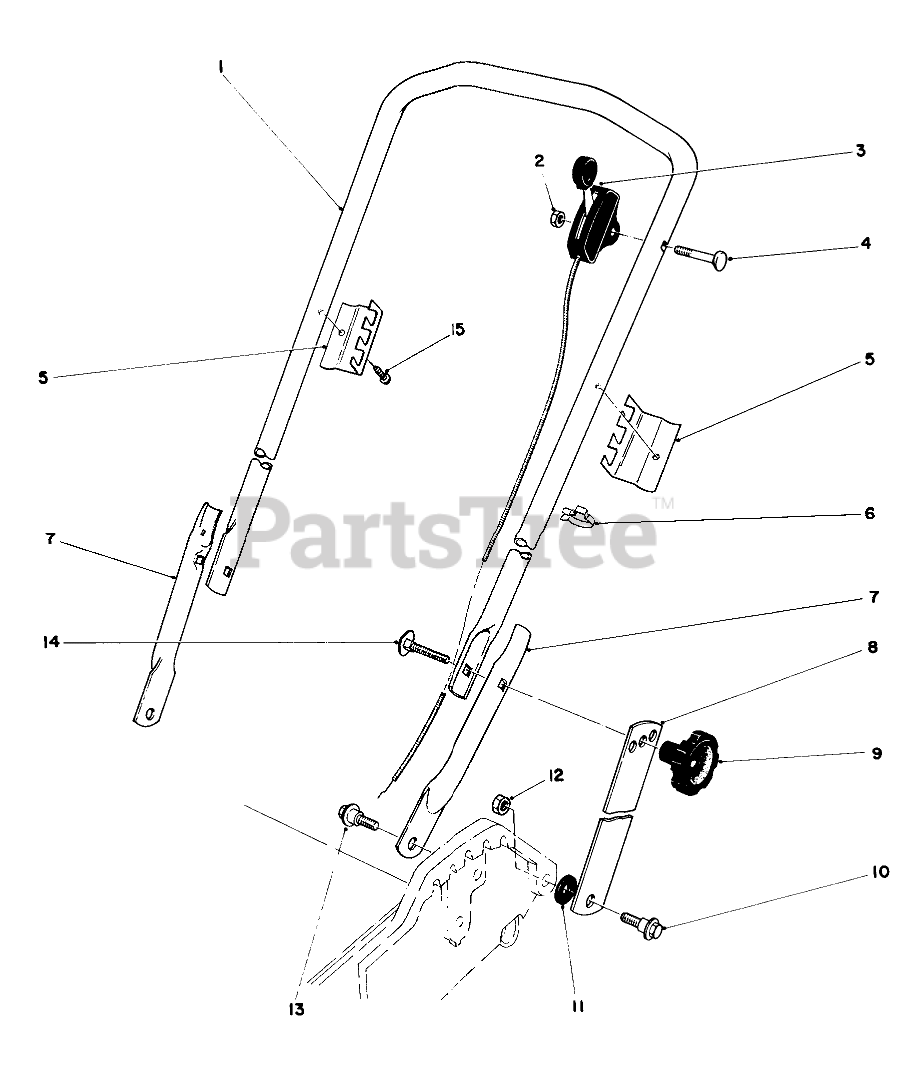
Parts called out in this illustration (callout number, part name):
1	Upper Handle (Incl. #3)
2	NUT-LOCK, NI
3	SERVICE THROTTLE CONTRO
4	SCREW-HANDLE
5	Bag Support
6	BOWDEN CLIP
7	Hand-Lower
8	Handle Latch
10	NUT-LOCK, NI
11	SCREW-SHOULDER
12	SPACER
13	SCREW-SHOULDER
14	5/16-18 X 2 HNDLE SCREW
15	SCREW-HWHTF
